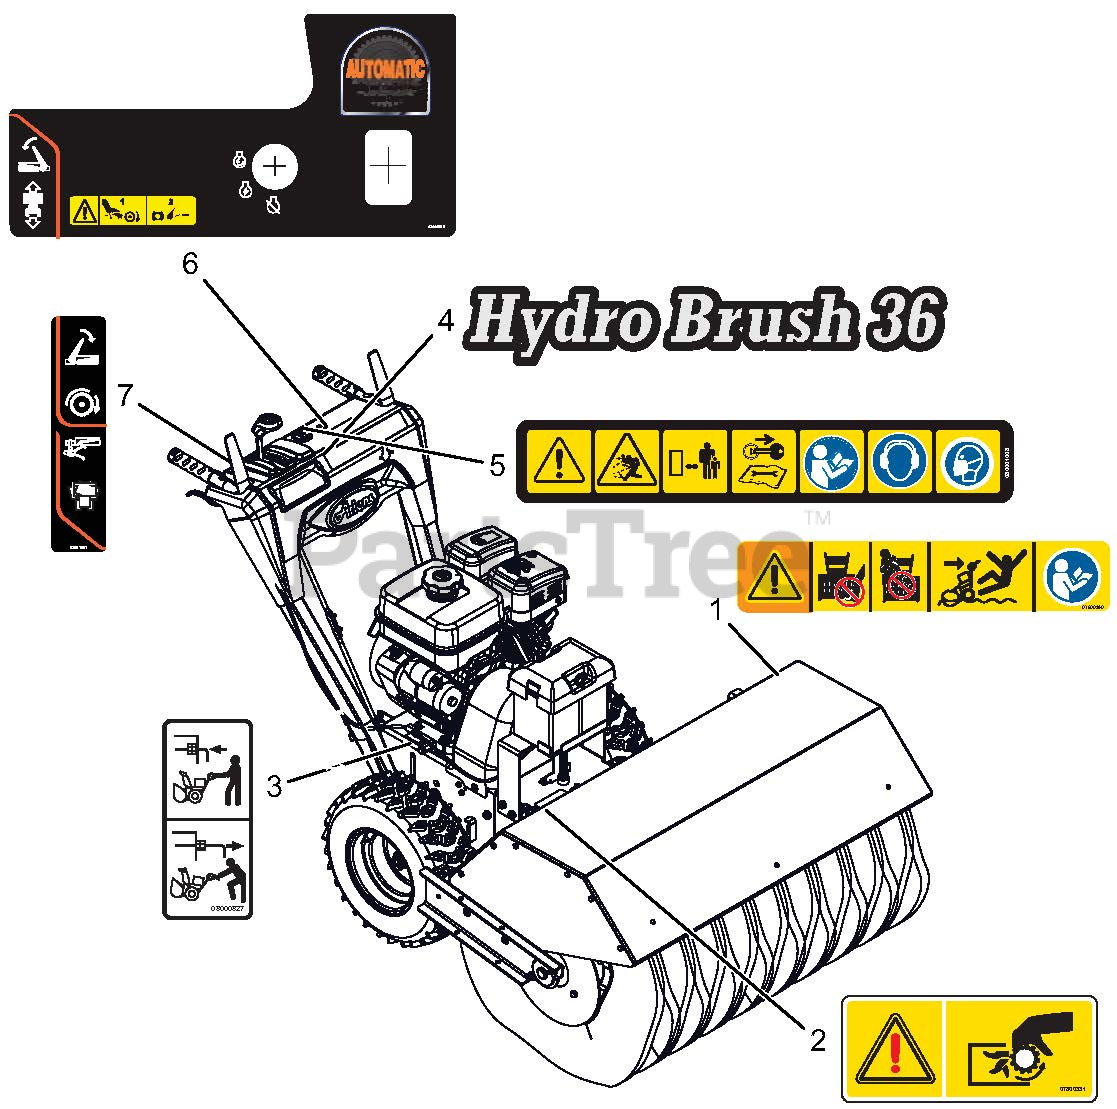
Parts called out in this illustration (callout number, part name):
1	DECAL, DANGER -POWER BRUSH-CE
2	DECAL, PTO WARNING
3	DECAL, BYPASS
4	DECAL, HYDRO BRUSH 36
5	DECAL, SAFETY, DASH, BRUSH
6	DECAL,CNTRL,LRG BRUSH,LH,HYDRO
7	DECAL,CONTROL,BRUSH,RH
